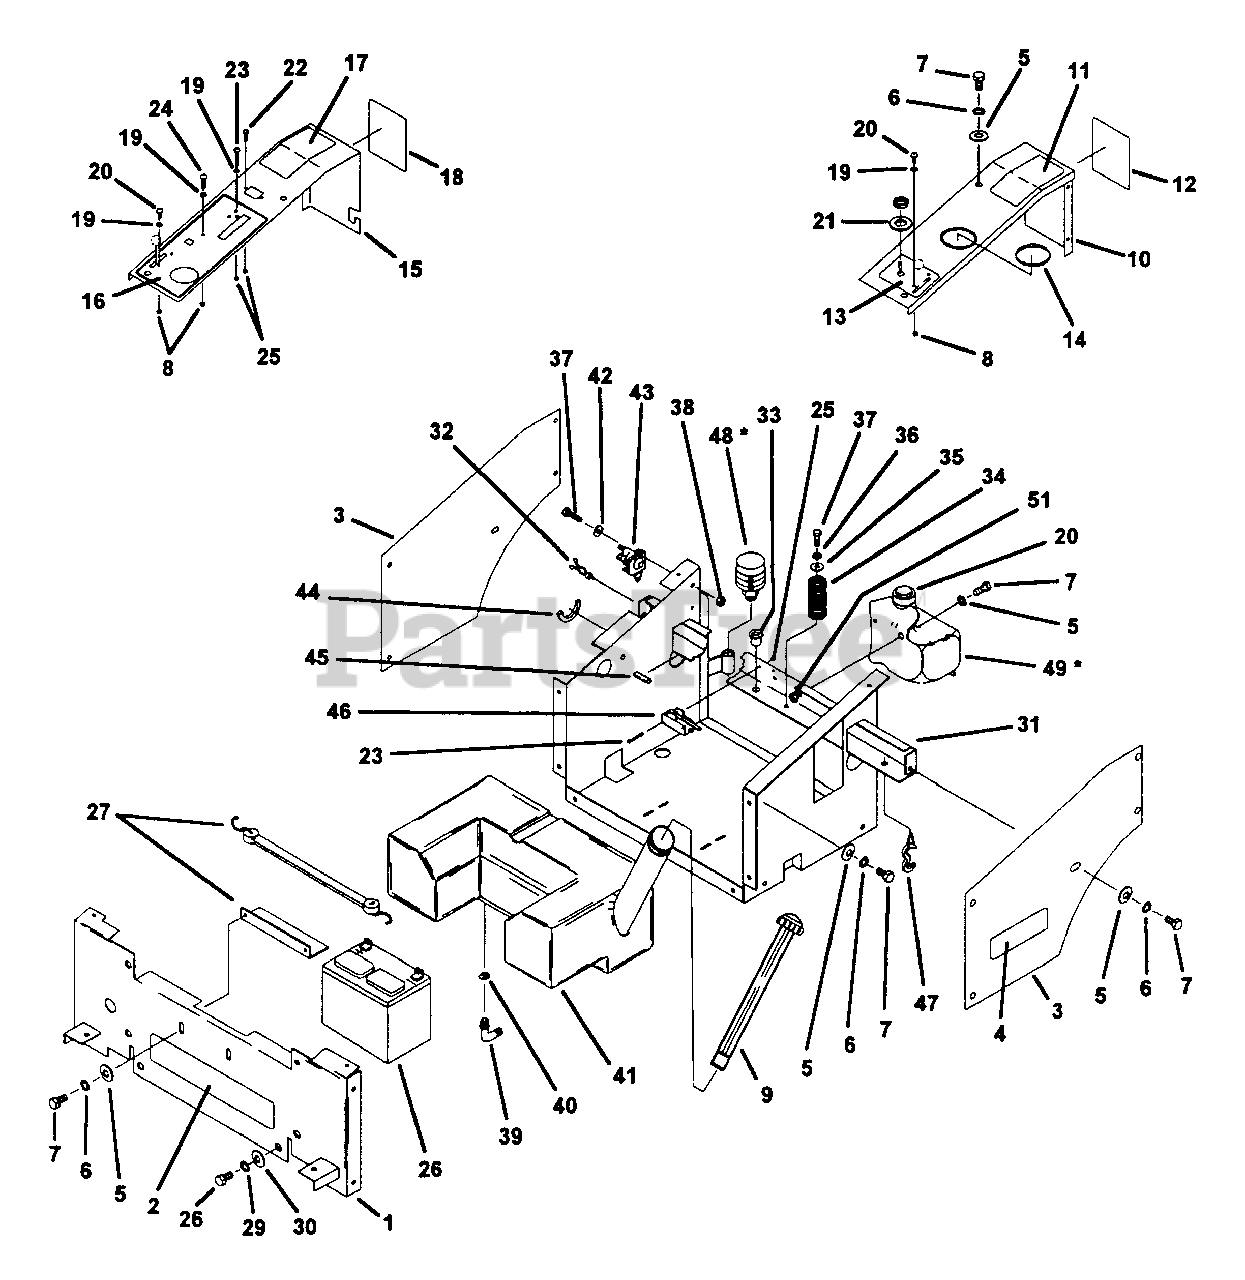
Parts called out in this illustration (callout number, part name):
1	SEAT SUPPORT FRONT ASSEMBLY
2	DECAL, SNAPPER
3	FENDER SKIRT
4	DECAL, I.D. "Z1202B" 12 HP MODEL
5	WASHER, FLAT STD. 5/16"
6	LOCKWASHER, 5/16" HEAVY SPRING
7	BOLT, 5/16-18 X 3/4" GR. 5
8	LOCKNUT, #8-32 NYLOC
9	FUEL GAUGE CAP
10	FENDER CAP (w/ decals) L.H. 12 HP
11	DECAL, CAUTION
12	DECAL, TOWING WARNING
13	DECAL, BLADE, 12 HP
14	TRIM, U-CHANNEL GAS TANK, 14, 18, 20 HP
15	FENDER CAP (w/ decals) R.H. 12 HP
16	DECAL, INSTRUMENT PANEL, 12 HP
17	DECAL, CAUTION
18	DECAL, BELT TENSIONING
19	WASHER, #8 FLAT
20	SCREW, MACHINE, #8-32 X 1/2"
21	D-WASHER
22	SCREW, MACHINE, #6-32 X 5/8"
23	SCREW, MACHINE, #6-32 X 1"
24	SCREW, MACHINE, #8-32 X 3/4"
25	LOCKNUT, #6-32 NYLOC
26	BATTERY 12 VOLT
27	BATTERY CLAMP ANGLE, 14, 18, 20 HP MODELS
29	LOCKWASHER, 3/8" HEAVY SPRING
30	WASHER, FLAT STD. 3/8"
31	SEAT SUPPORT WELDMENT
32	BLIND HOLE KURLY
33	BUSHING, PLASTIC
34	SEAT SPRING
36	LOCKWASHER, 1/4" SPLIT SPRING
37	BOLT, 1/4-20 X 3/4" GR. 5
38	LOCKNUT, 1/4-20 NYLOC
39	ELBOW, 90D 1/4NPT X 1/4 BARB
40	CLAMP, .31 MIN. X .87 MAX. HOSE DIA.
41	FUEL TANK
42	WASHER FLAT STD. 1/4"
43	SOLENOID, 12V STARTER
44	TRIM, U-CHANNEL
45	EDGE GUARD
46	SWITCH, ENCL, SPDT 15A HINGED LEVER
47	FITTING 1/2" ROSE BUD CLIP
48	RESERVOIR CUP W/ CAP
49	TANK, 1.5 QT.
51	NUT, HEX. 5/16-18 NYLOC
